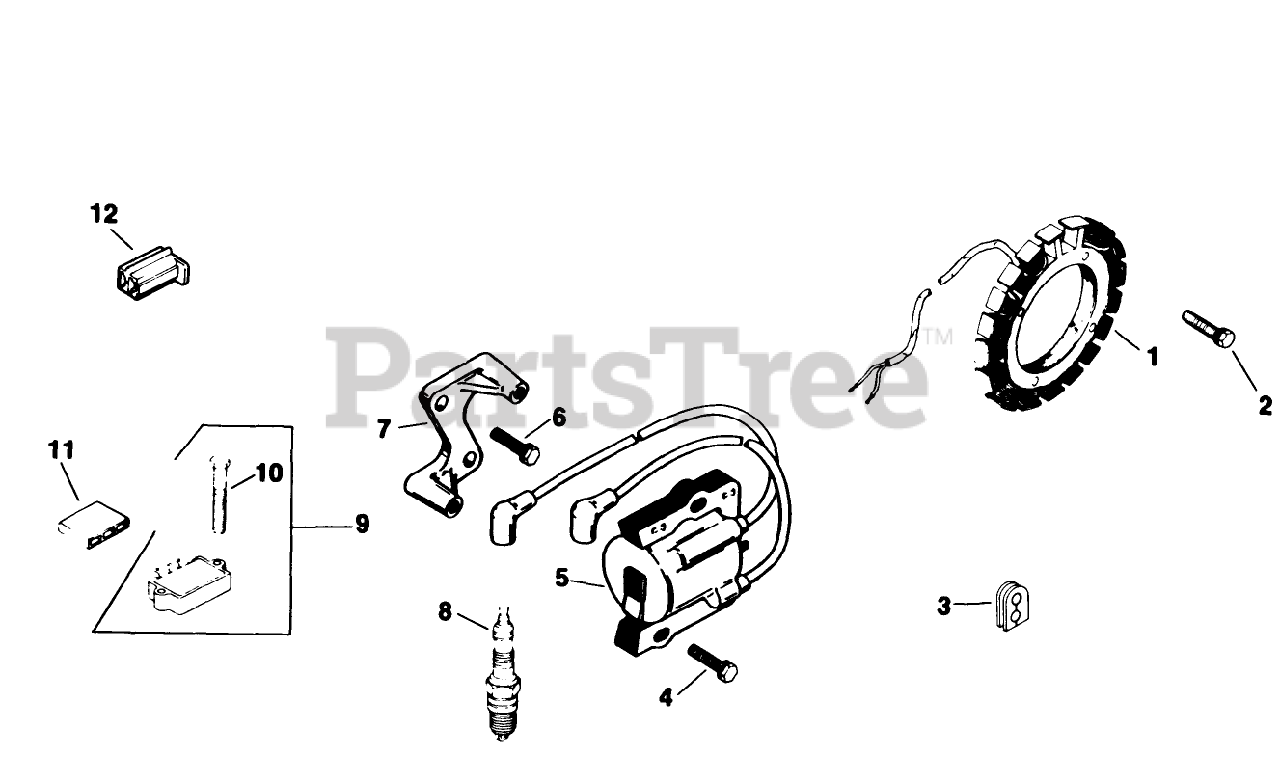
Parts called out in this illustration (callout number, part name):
1	Stator
2	Screw
3	Grommet
4	Screw-Hex Washer Hd.
5	Module-Ignition
6	Screw-Hex Washer Hd.
7	Bracket-Module
8	Plug-Spark
9	Kit-Rectifier-Regulator (Incl. Ref. #10)
10	Screw
11	Connector
12	Connector
